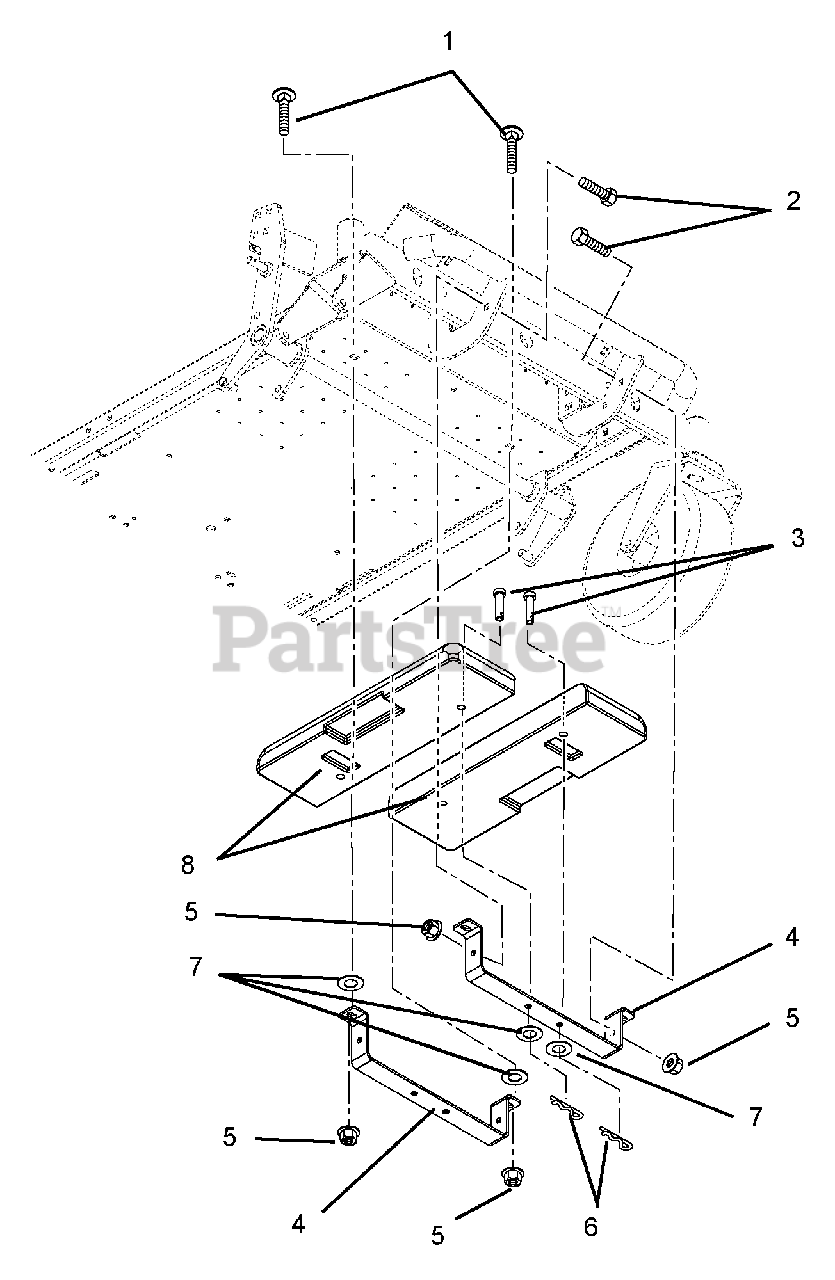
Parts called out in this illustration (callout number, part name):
1	Bolt-Round Head Square Neck .38-16 x 1.00 Grade 5
2	Bolt-Hex .38-16 x 1.00 Grade 5
3	Pin-Clevis .494 x 2.50
4	Bracket, Weight
5	Nut-Locking-Top-Flange .38-16
6	Pin-Hair-External .12 x .31 x 2.37
7	Washer-Flat-Steel .515 x 1.625 x .250
8	Counterweight
